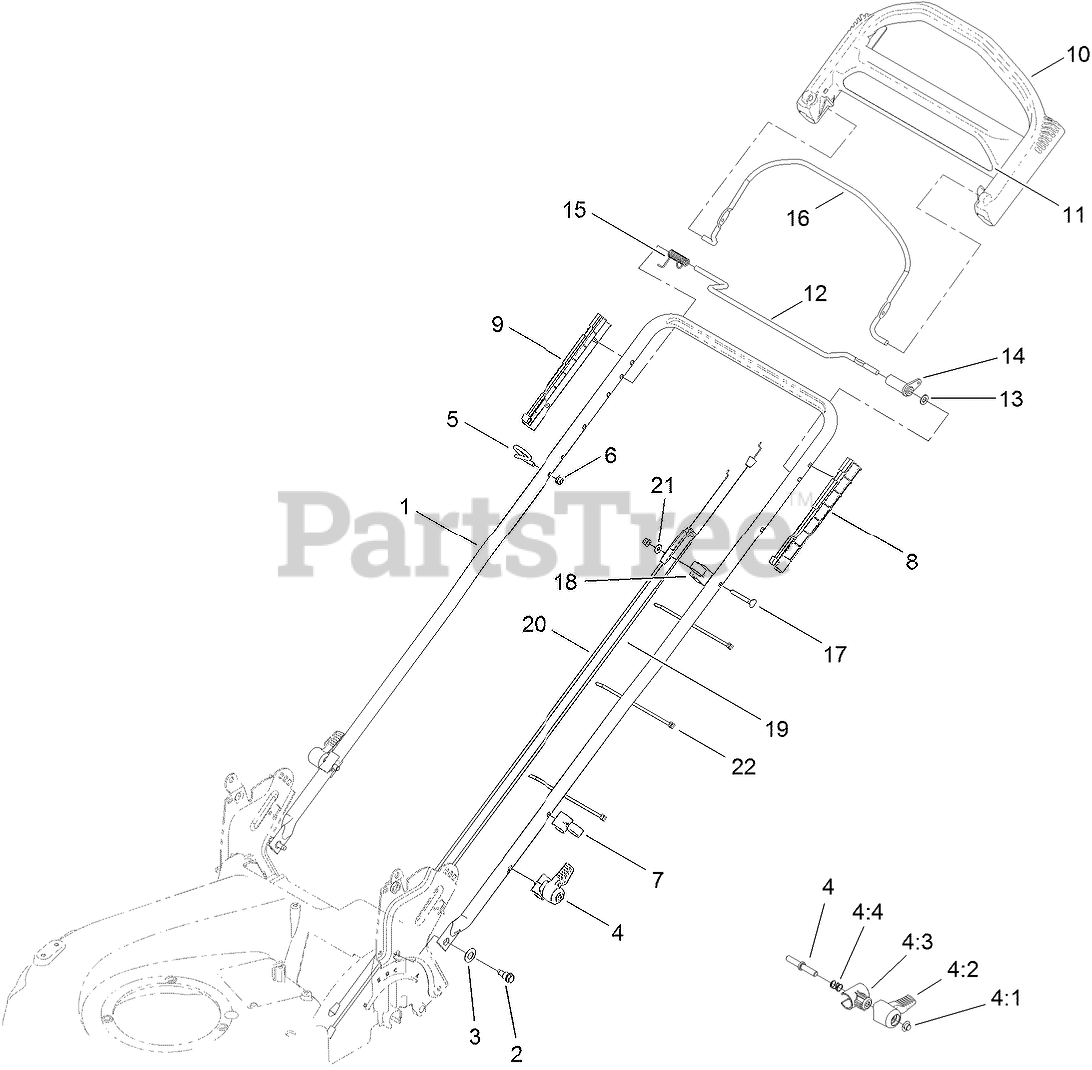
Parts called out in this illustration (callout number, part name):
1	HANDLE
2	BOLT-SHOULDER
3	WASHER-SPRING, CONICAL
4	QUICK RELEASE ASM
4:1	NUT-PUSH
4:2	LEVER
4:3	ANCHOR-SPRING
4:4	SPRING-COMPRESSION
5	GUIDE-ROPE
6	NUT-LOCK, NI
7	GUIDE-CABLE
8	GUIDE-LH
9	GUIDE-RH
10	HANDLE-CONTROL
12	BAR-CONTROL, TRACTION
13	WASHER-PLAIN
14	LEVER-TRACTION
15	Spring-Torsion
16	Bail-Brake
17	SCREW
18	ANCHOR-CABLE
19	CABLE-TRACTION
20	CABLE-BRAKE
21	WASHER-FLAT
22	TIE-CABLE
